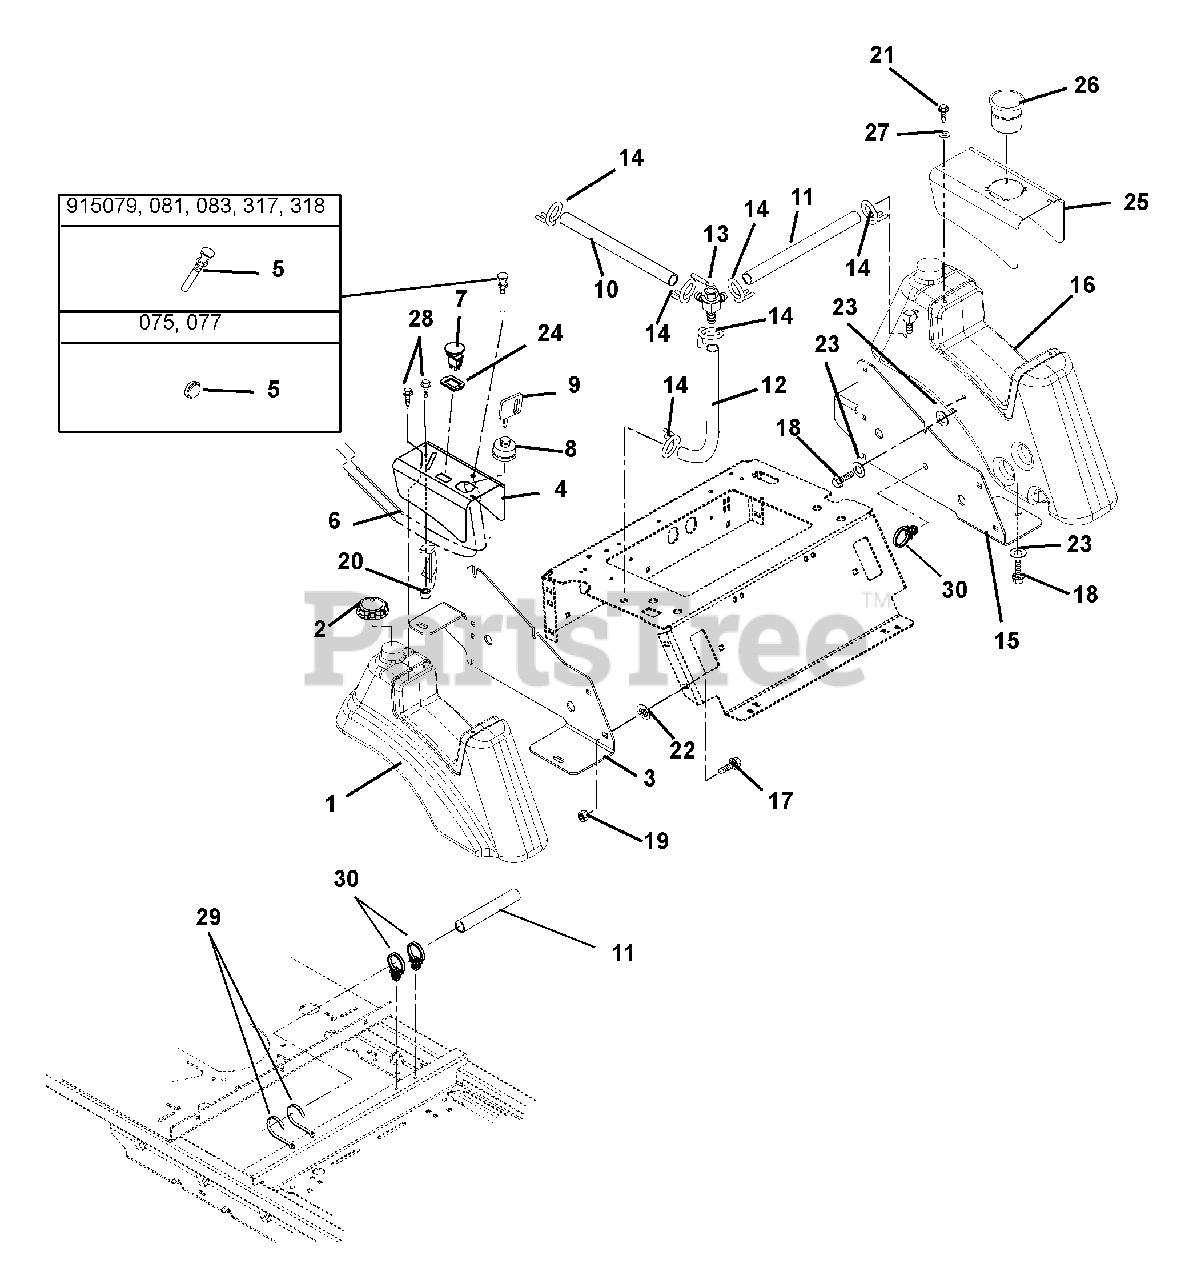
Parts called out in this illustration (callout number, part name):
1	FUEL TANK, RH
2	FUEL CAP
3	SEAT PLATE, RH
4	RH CONSOLE
5	CHOKE CABLE
6	THROTTLE CABLE
7	SWITCH, CLUTCH
8	KEY SWITCH
9	KEY -W/CAP
10	GAS LINE-BULK 1/4" I.D.
11	GAS LINE-BULK 1/4" I.D.
12	GAS LINE-BULK 1/4" I.D.
13	VALVE, FUEL
14	CLAMP-HOSE WIRE .490/.510X.116
15	SEAT PLATE, LH
16	FUEL TANK, LH
17	@BLT-RDHDSQNK .38-16X1.00 G5YZ
18	BLT-SERHFWH .312-18X.75 YWZC
19	@NUT-LK-NYL-FLG .38-16 YWZC
20	@NUT-LK-NYL 10-24 W/INSRT YWZC
21	SCR-MCH 10-24X3/8 SL HEX YWZC
22	RETAINER, .38 PUSH-ON
23	WSHR-FL-STL .328X1.0X.094 YWZC
24	SHIM,PTO SW (DELTA #972301)
25	LH CONSOLE
26	CUPHOLDER
27	WASHER, FENDER 3/16X3/4 YWZC
28	@SCR-MCH 10-24X.50 HWH YWZC
29	CABLE TIE, .18X8.5 50 LB PUSH
30	WIRE CLIP
